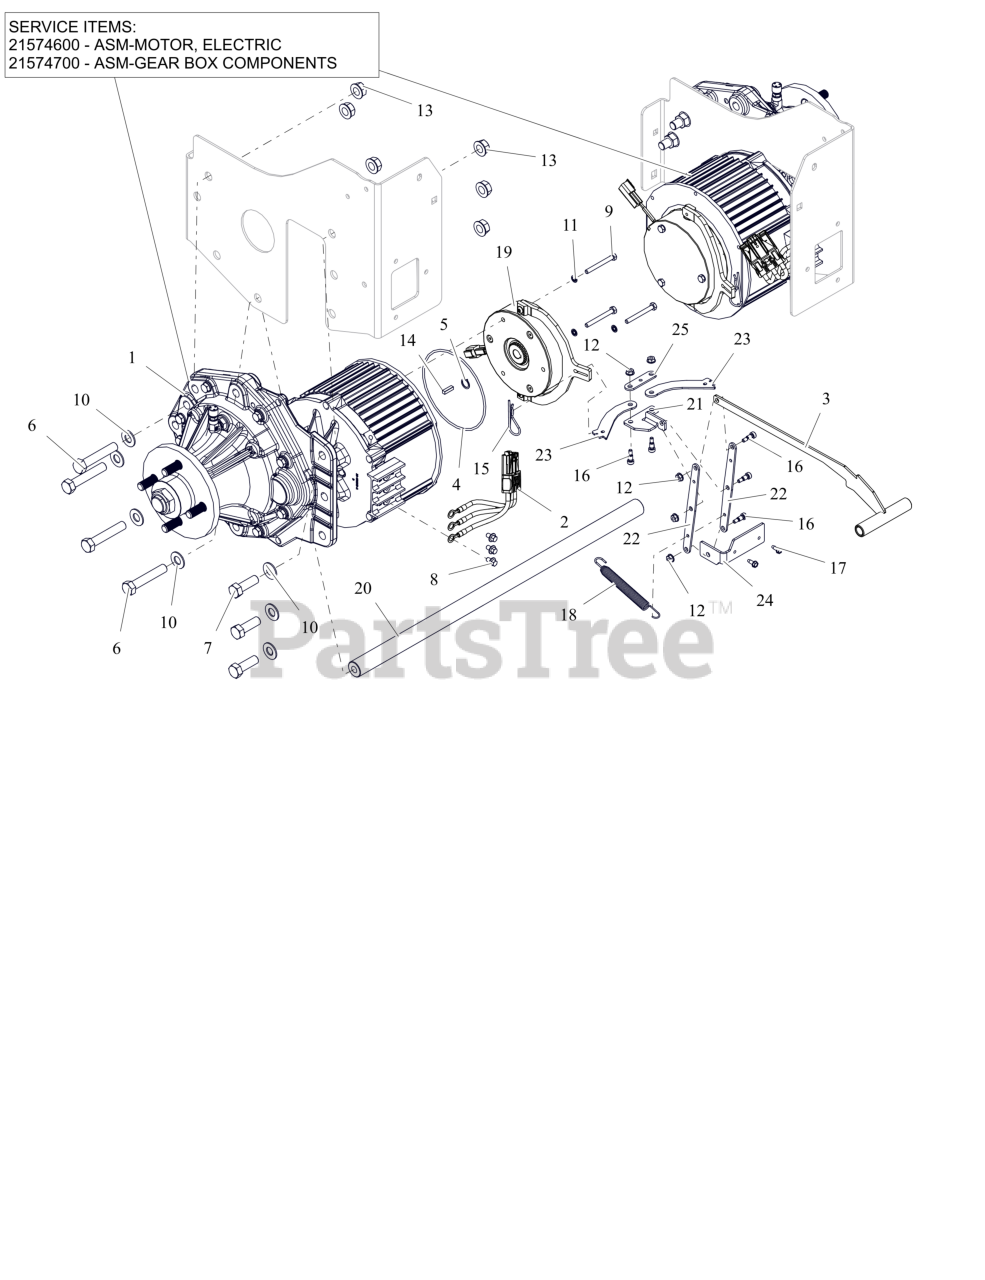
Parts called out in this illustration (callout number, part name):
1	ASM, WHEEL DRIVE
1	ASM-MOTOR, ELECTRIC
1	ASM-GEAR BOX COMPONENTS
2	HARNESS, PHASE - DRIVE MOTOR
3	WLDMT, BRAKE RELEASE
4	O-RING 126MM IDX3MM
5	RING, RETAINING-EXTERNAL 25MM X 1.2MM
6	BLT, HEX .50-13X2.75 G8 ZCC
7	BLT, HEX 0.5-13X1.5 GR8 ZCC
8	BLT,HEX M6-1X10 G8.8 ZCC
9	BLT,HEX M6-1X55 EP30 G8.8 ZCC
10	WSHR, FLT .557X1.040X.102 ZCC
11	WSHR-FL-STL, SEAL 6MMX11MMX1MM
12	NUT, FLG-TOP LK #10-24 GF ZCC
13	NUT, FLG-CTR LK .500-13 GG ZCC
14	KEY-STR 5X5X18MM RD ENDS
15	PIN, HAIR-#7 .094X2.31 ZC120
16	BLT-SHLDR .25X.375
17	SCR,TAP #10-24X.50 HWH TR ZCC
18	SPRING, SWIVEL HOOK EXTENSION
19	BRAKE, MOTOR
20	SHAFT, TRANSAXLE SUPPORT (BLACK)
21	LINK, T
22	LINK, MIDDLE
23	LINK, PUSH
24	PIVOT, BRAKE LINK MAIN
25	PLATE, BRAKE PULL DOUBLER
